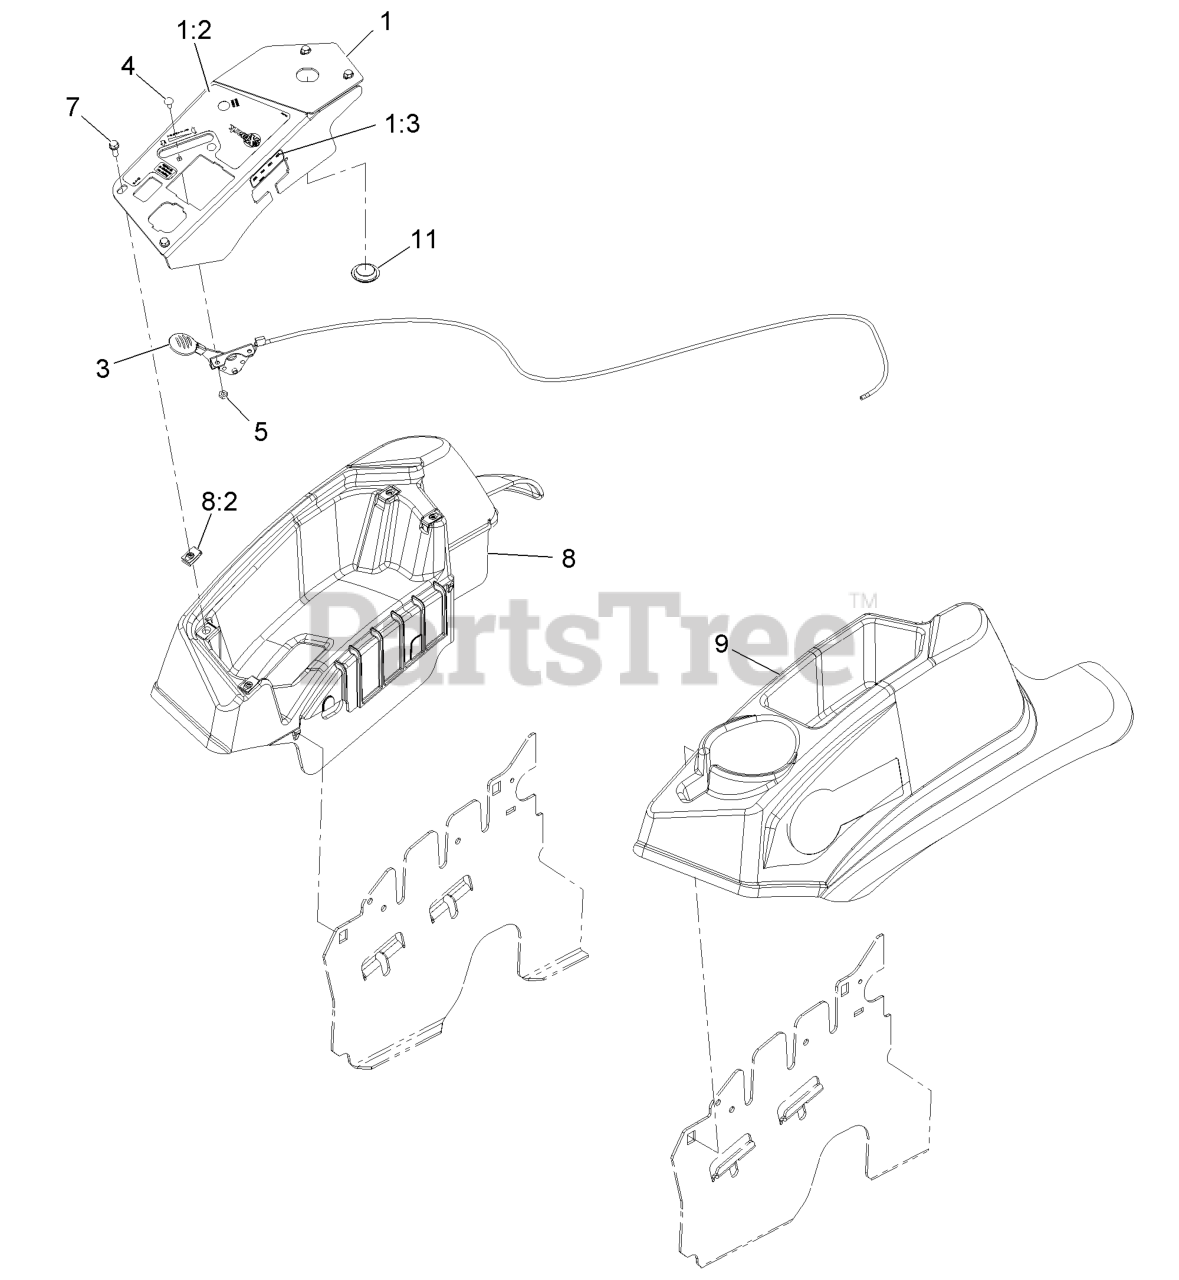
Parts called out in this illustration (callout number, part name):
1	ASM,CONTROL PANEL W/DECAL
1:2	DECAL,CONTROL PANEL EFI
1:3	DECAL-FUSE
3	ASM,THROTTLE CABLE
4	BOLT-CARR
5	NUT-LOCK, NI
7	SCREW-HWH
8	CONSOLE,RH AS ASM
8:2	Nut-Retainer-Panel 1/4-20
9	CONSOLE, LH AS
11	PLUG-PLASTIC
